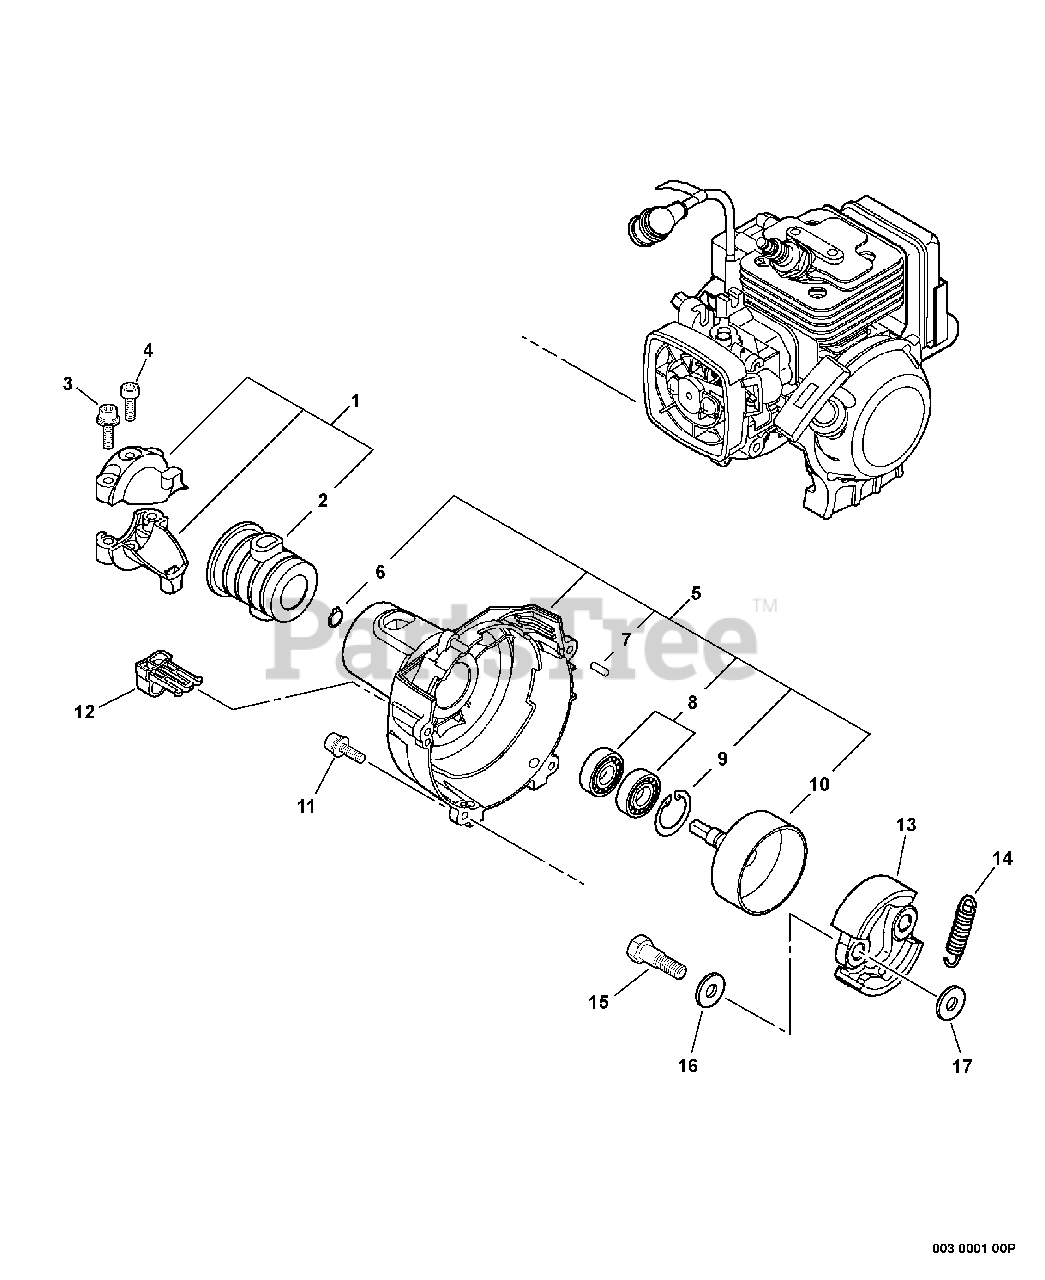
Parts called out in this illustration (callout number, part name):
1	HOLDER KIT, MAIN PIPE
2	CUSHION
3	BOLT 5×25
4	BOLT 5×12
5	FAN CASE ASSY
6	RING, RETAINING - 12
7	PIN, LOCATING 4
8	BEARING, BALL 6001
9	RING, SNAP 28
10	DRUM, CLUTCH
11	BOLT 4×16
13	SHOE, CLUTCH
14	SPRING, CLUTCH
15	BOLT, CLUTCH 8×7.9×M6
16	WASHER, SPRING 8.5×16×0.5
17	WASHER 6.2×19×1.0
